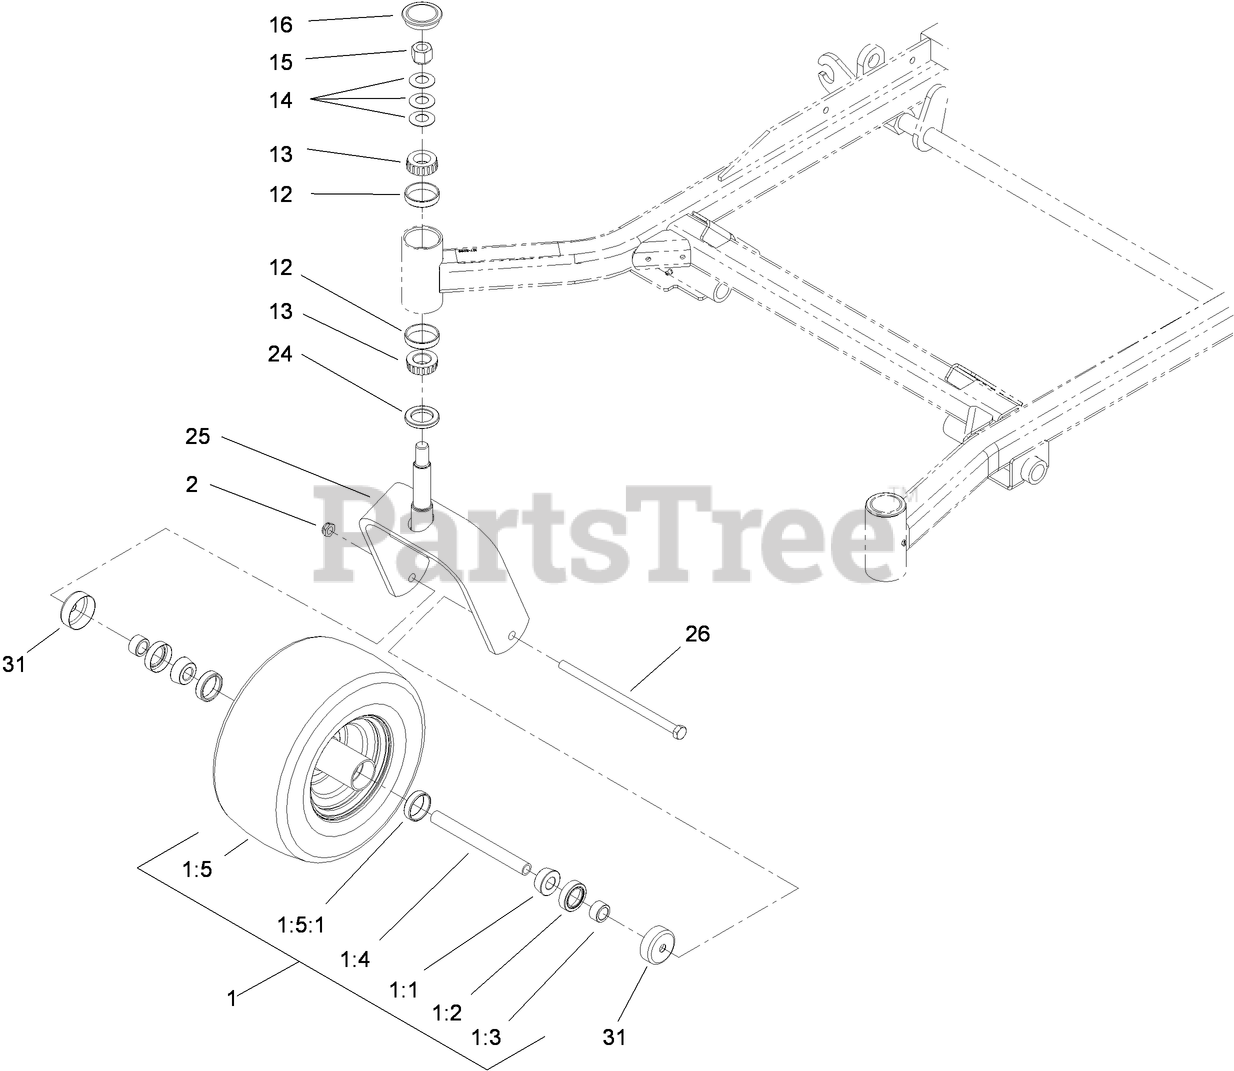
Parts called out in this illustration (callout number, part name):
1	WHEEL AND TIRE ASM
1:1	BEARING-CONE, TAPER
1:2	SEAL-CASTER
1:3	SPACER-NUT
1:4	AXLE-CASTER
1:5	WHEEL AND TIRE ASM
1:5:1	BEARING-CUP
2	NUT-LOCK, NI
12	BEARING-CUP, TAPERED
13	BEARING-CONE, TAPERED
14	WASHER-BELLVILLE
15	NUT-LOCK, NI
16	CAP-GREASE
24	SEAL-GREASE
25	CASTER-FORK
26	Screw-HH
31	GUARD-SEAL
